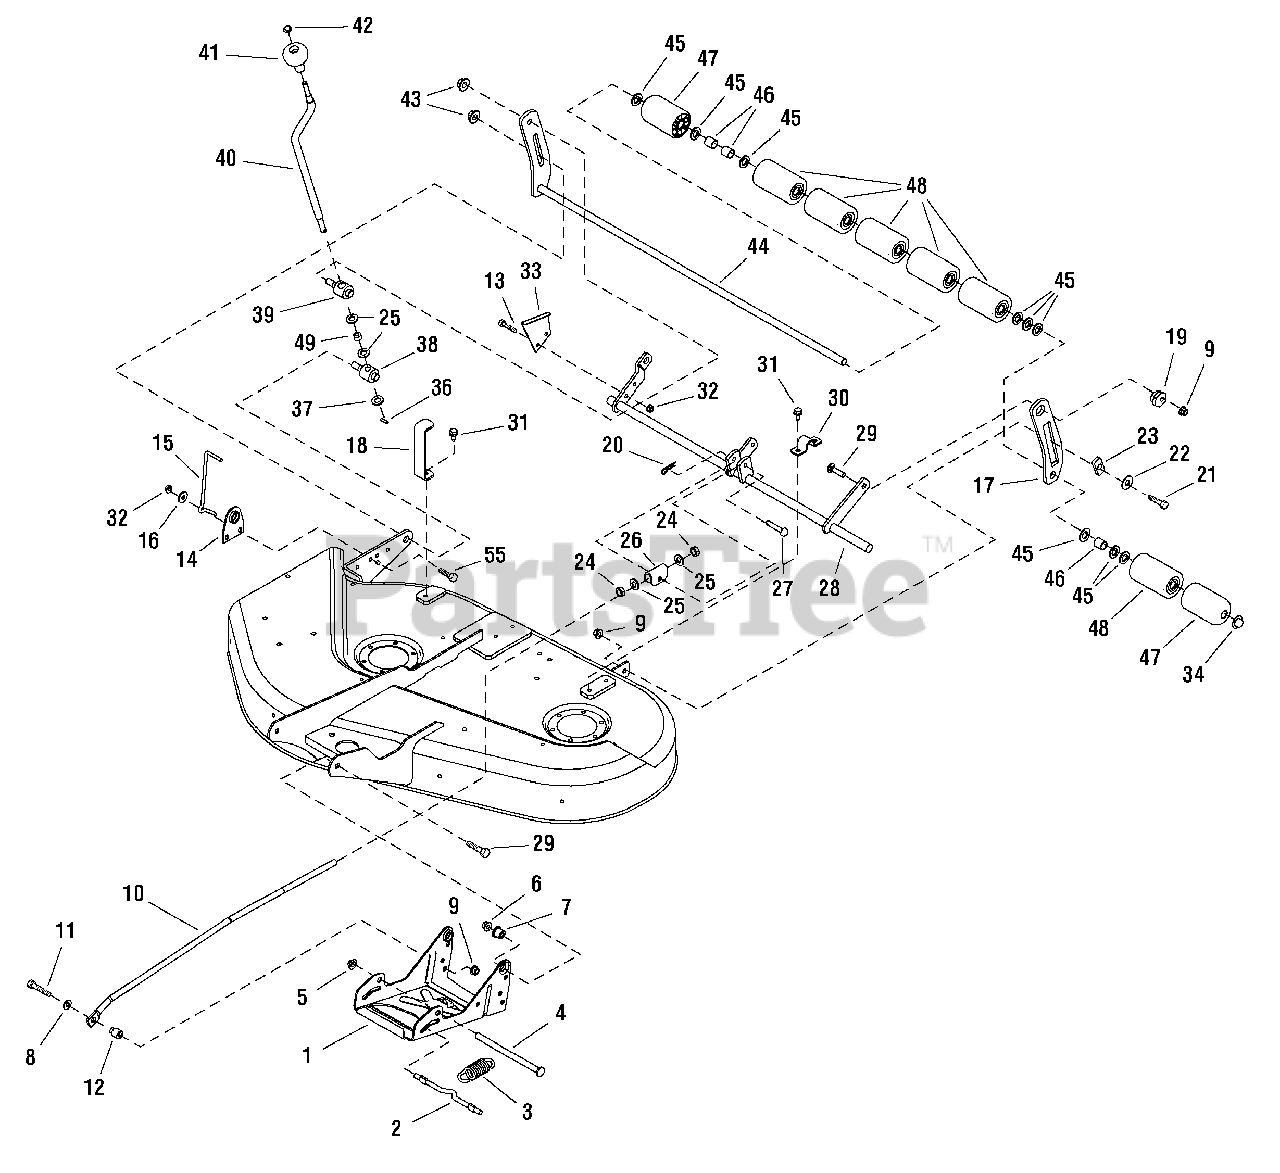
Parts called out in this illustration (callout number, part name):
1	HITCH, Mower
2	ROD, 3/8 Diameter
3	SPRING, Extension
4	ROD, 1/2 Diameter
5	NUT, Push for 1/2 Diameter Stud Capped
6	NUT, Hex Flange 3/8-16 ESNA
7	SPACER
8	WASHER, 3/8
9	NUT, Hex Toplock Spiral Lock Flange, 3/8-16
10	ROD, E-Coat, 1/2-13 x 5.3
11	CAPSCREW, Hex Head 3/8-16 x 1-3/4 G8
12	SPACER, 3/8 x 3/4 x 15/16
13	CAPSCREW, Hex Head 5/16-18 x 7/8 G5
14	PLATE, Support
15	ROD, 1/4 Diameter, Indicator, Cutting Height
16	WASHER, 5/16
17	BAR, Roller Square Slot
18	UPSTOP
19	NUT, Hex Adjusting
20	CLIP, Hair Pin
21	BOLT, Shoulder 3/8-16 G5
22	WASHER, 1/2
23	SLIDE
24	NUT, Hex Jam 1/2-13
25	WASHER, 1/2
26	TRUNNION
27	PIN, Round Head Drilled, 3/8 x 2
28	SHAFT ASSEMBLY, Rocker 38" (96cm)
29	CARRIAGE BOLT, 3/8-16 x 1-1/2 G5
30	STRAP, Roller
31	SCREW, Hex Washer Head Taptite 5/16-18 x 3/4
32	NUT, Hex Flange 5/16-18, Whiz Lock Small
33	BRACKET, Height of Cut
34	NUT, Push for 5/8 Diameter Stud Capped
36	PIN, Spring
37	WASHER, Detent
38	TRUNNION, 1-1/4
39	TRUNNION, 1-1/4
40	CRANK, Height Adjusting
41	KNOB, Spinner
42	NUT, Push Pal 5/8 Diameter Stud Capped
43	NUT, Hex Flange 1/2-13 Two-Way Lock
44	SHAFT ASSEMBLY, Roller 38"
45	WASHER, 5/8
46	SPACER, Split
47	ROLLER, Rounded
48	ROLLER
49	SPACER
55	CAPSCREW, Hex Head, 5/16-18 x 1-1/4
